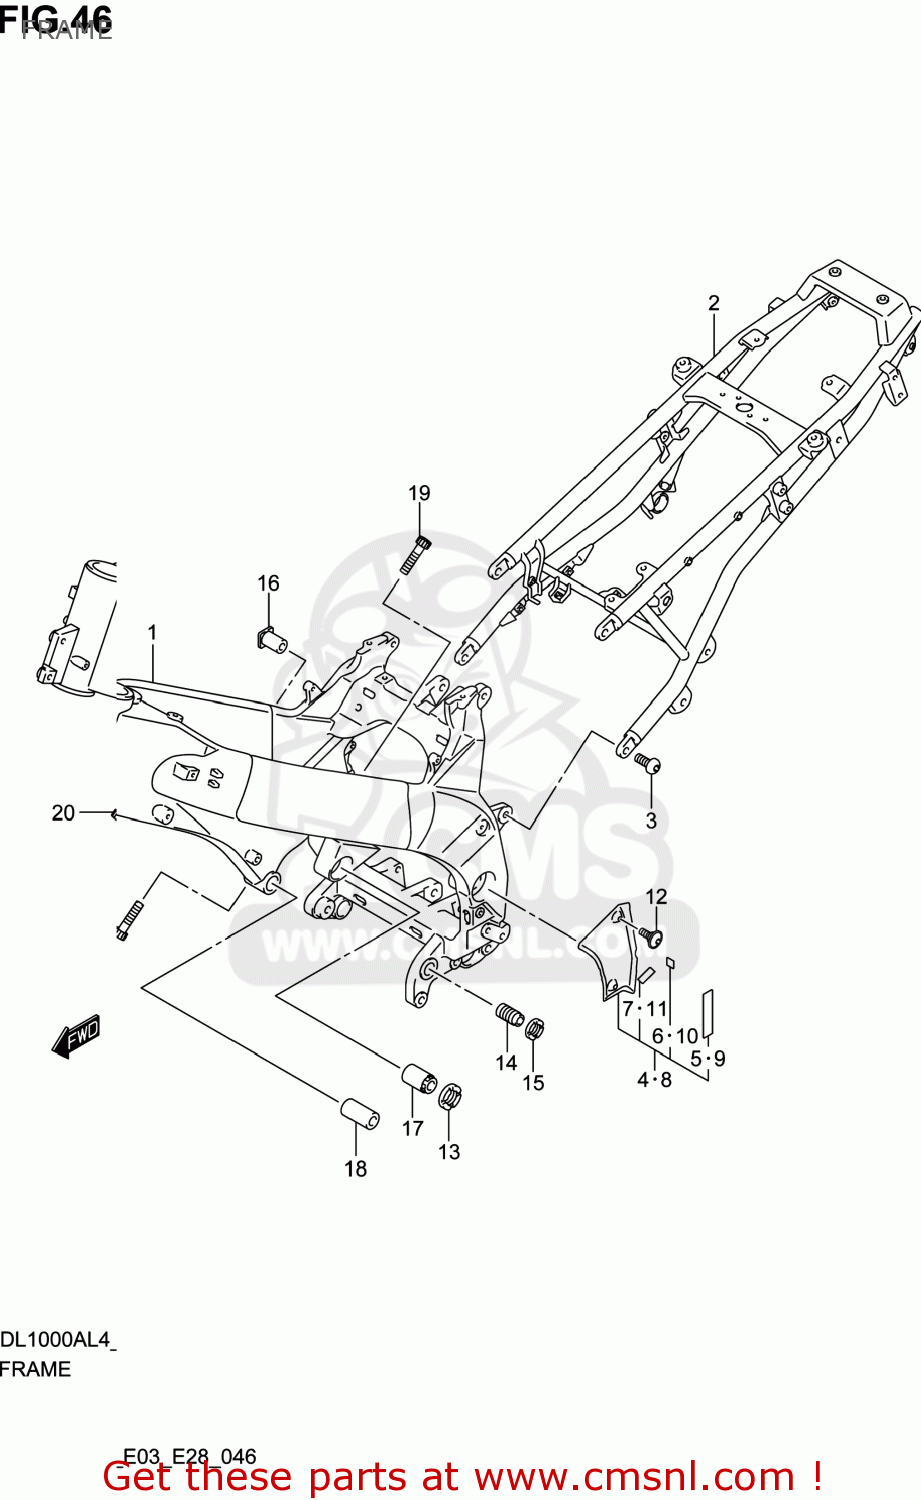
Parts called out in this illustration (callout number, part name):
1	FRAME(BLACK)
2	RAIL,SEAT(SILVER)
3	BOLT(10X25)
4	COVER,PIVOT,R
5	PROTECTOR(20X90)X2
6	CUSHION,RR COVER NO.2
7	CUSHION,PIVOT COVER NO.2
8	COVER,PIVOT,L
9	PROTECTOR(20X90)X2
10	CUSHION,RR COVER NO.2
11	CUSHION,PIVOT COVER NO.2
12	BOLT(5X13)
13	NUT,CRANK CASE ADJUST CTR
14	BOLT,CASE LWR & RR HEAD ADJ
15	NUT,CRANK CASE ADJUST LWR
16	SPACER,MOUNTING RR UPR,R
17	BOLT,CRANK CASE ADJUST
18	SPACER,ENG HEAD MTG RR,L
19	BOLT
20	BOLT
